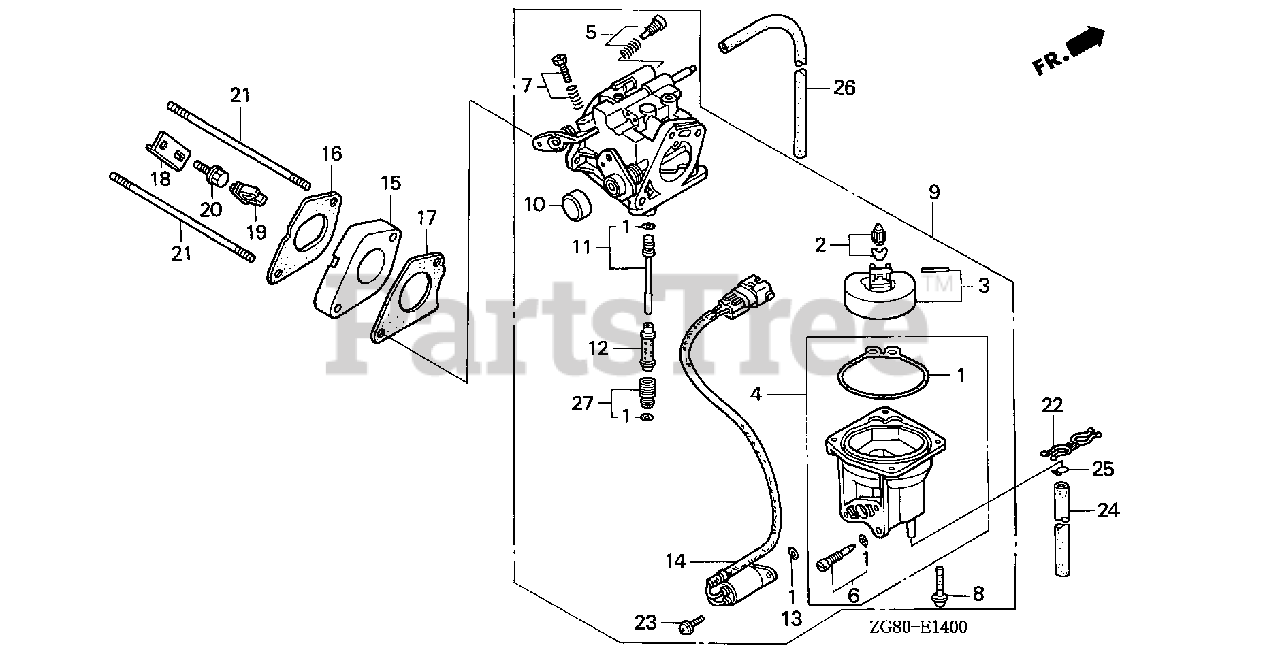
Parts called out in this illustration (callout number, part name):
1	GASKET SET
2	VALVE SET, FLOAT
4	CHAMBER SET, FLOAT
6	SCREW SET, DRAIN
8	SCREW-WASHER
9	CARBURETOR ASSY. (BG19B A)
10	CAP, CHOKE DUST
11	JET SET (#48)
12	NOZZLE, MAIN
13	O-RING (5.8X1.9)
14	VALVE ASSY., SOLENOID
15	INSULATOR, CARBURETOR
16	GASKET, INSULATOR
17	GASKET, CARBURETOR
18	BRACKET, HARNESS CLIP
19	CLIP B, AIR TEMPERATURE SWITCH WIRE
20	BOLT, FLANGE (6X14) (CT200)
21	BOLT, STUD (6X113)
22	CLIP, WIRE HARNESS
23	SCREW-WASHER (5X12)
24	BULK HOSE, FUEL (4.5X3000) (4.5X380)
25	CLIP, TUBE (B8)
26	BULK HOSE, VACUUM (3.5X1000) (3.5X250)
27	JET SET, MAIN (#88)
27	JET SET, MAIN (#92)
27	JET SET, MAIN (#98)
